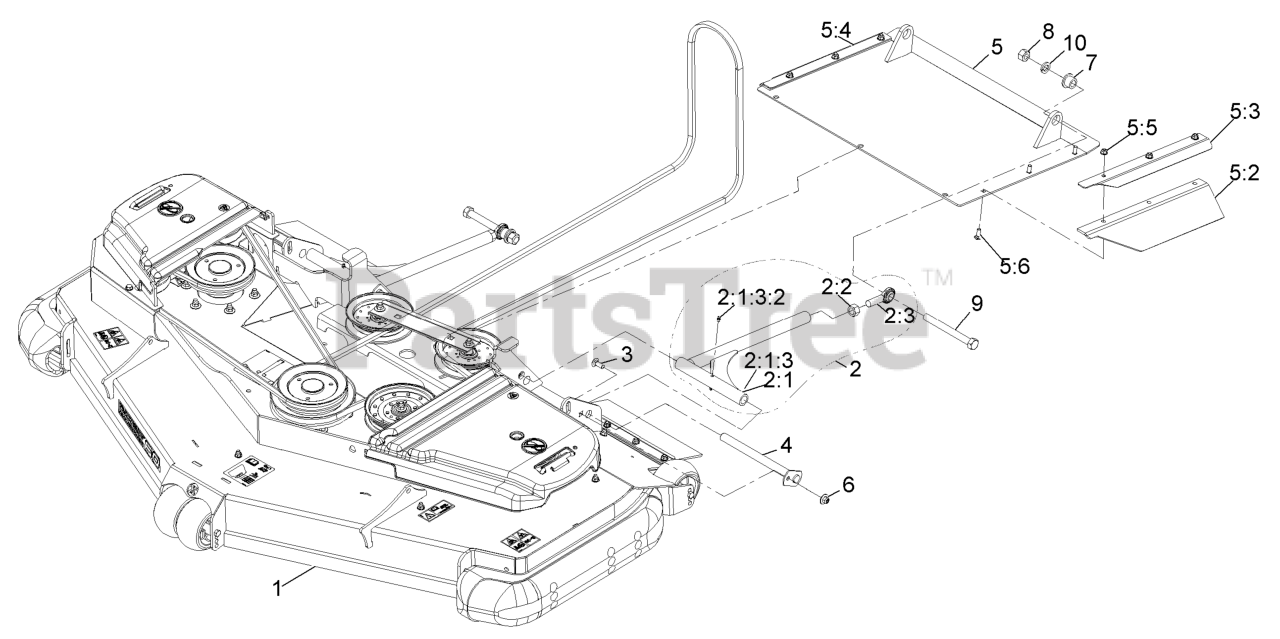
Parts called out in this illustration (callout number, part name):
1	ASM-Deck Complete Rd60
2	ASM,DECK STRUT XS 60
2:1	STRUT-DECK
2:1:3	Tube And Zerk ASM
2:2	NUT-HEX
2:3	BALLJOINT-SPHERICAL
3	BOLT-CARR
4	PIN-STRUT
5	ASM-DISCHARGE TUNNEL RD60
5:2	FLAP-RD TUNNEL SIDE
5:3	BRKT-RD TUNNEL FLAP LH
5:4	BRKT-RD TUNNEL FLAP RH
5:5	NUT-HF, NI
5:6	SCREW-CARR
6	Nut-Nyloc 3/8-16 Flg
7	BUSHING-FLANGE
8	NUT-HEX
10	WASHER-LOCK
